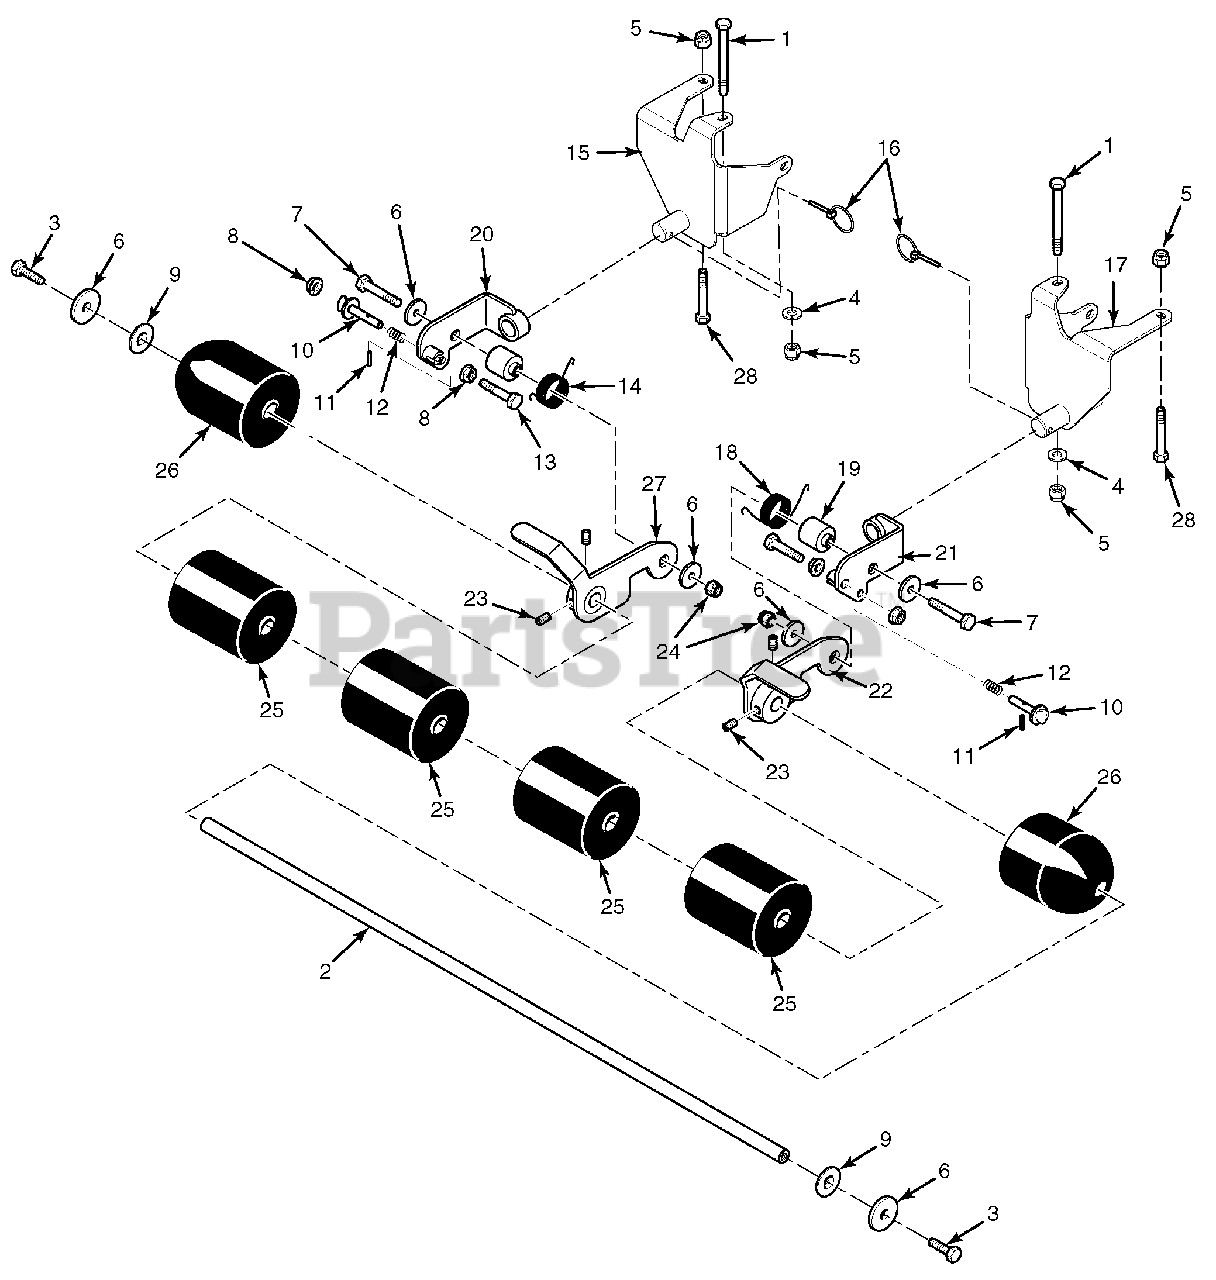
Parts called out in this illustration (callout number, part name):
1	Bolt, Hex Head 5/16-18 x 4-1/2"
2	Roller Shaft
3	Bolt, Hex Head 3/8-16 x 1" (Special Lock)
4	Flatwasher, 5/16-.378 x .875 x .083
5	Nut, Elastic Stop 5/16-18
6	Flatwasher, 3/8-.406 x 1-1/2" 7 Gauge
7	Bolt, Hex Head 3/8-16 x 2-3/4"
8	Nut, Serrated Flange 3/8-16
9	Flatwasher, 3/4-.812 x 1-3/8 x .100
10	Pin, Lift Latch
11	Pin, Slotted Spring 5/32" x 7/8"
12	Spring, Lock Pin
13	Bolt, Hex Head 3/8-16 x 2-1/2"
14	Spring, Torsion LH
15	Mounting Bracket Weldment, LH
16	Quick Pin, .188 Dia.
17	Mounting Bracket Weldment, RH
18	Spring, Torsion RH
19	Hub, Striper
20	Pivot Weldment, LH
21	Pivot Weldment, RH
22	Hinge Weldment, RH
23	Set Screw, 3/8-16 x 1/2"
24	Nut, Elastic Stop 3/8-16
25	Wheel, Striper
26	Wheel, Striper End
27	Hinge Weldment, LH
28	Bolt, Hex Head 5/16-18 x 3-1/4"
